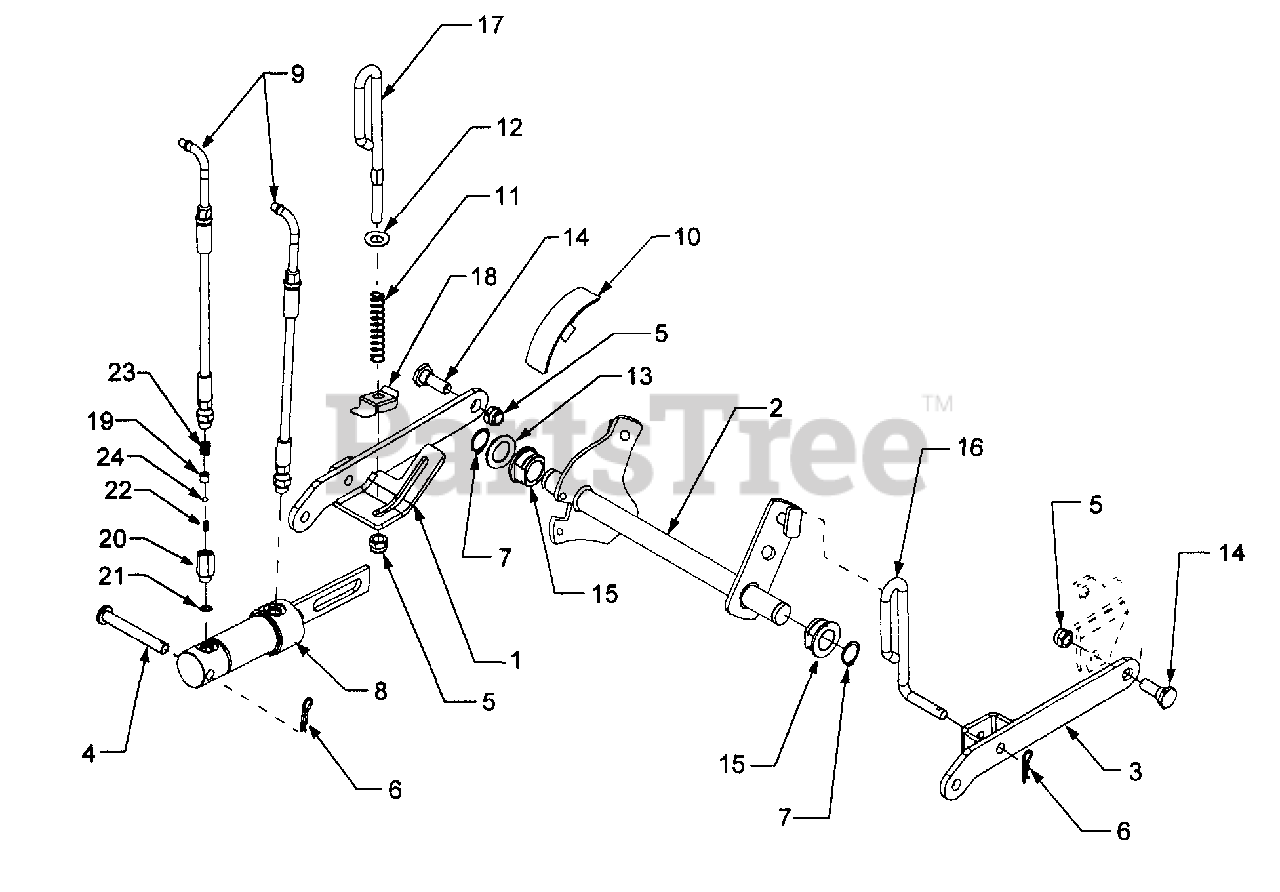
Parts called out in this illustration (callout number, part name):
1	Link, LH Lift
2	Shaft Assembly, Lift
3	Link, RH Lift
4	Pin, Clevis, .5 x 3.75
5	Nut, Hex Lock, 1/2-13
6	Pin, Internal Cotter
7	Snap Ring, 1.0 Dia. Shaft
8	Cylinder, Center Lift
9	Hose, Lift
10	Indicator, Lift Position
11	Spring, Compression
12	Washer, Flat, .536 x .93 x .050
13	Washer. Flat, 1.0 x 1.7 x .10
14	Shoulder Screw
15	Bearing, Flange w/Flats
16	Rod, RH Lift
17	Rod, LH Lift
18	Stop Bracket, Lift Rod
19	Body, Center Check Valve
20	Housing, Check Valve
21	O-Ring
22	Spring, Compression
23	Spring, Compression
24	Ball, Detent
